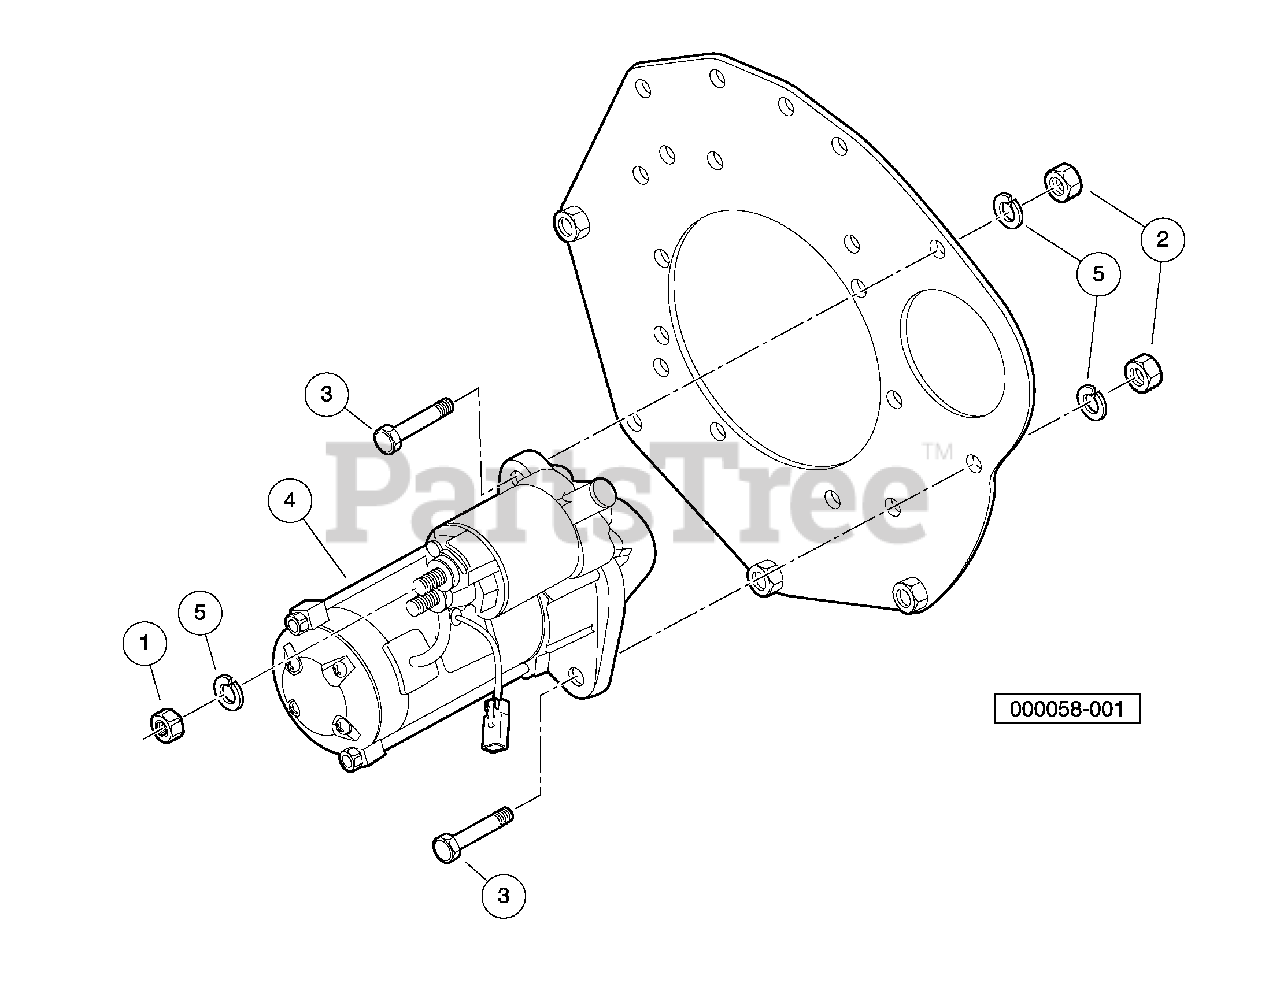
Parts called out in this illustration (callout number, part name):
1	Nut, D722, Starter
2	Nut, M8, Plate
3	Bolt, M8 X 1.25 X 28
4	Motor, Starter
5	Washer, Spring, D722, Starter
